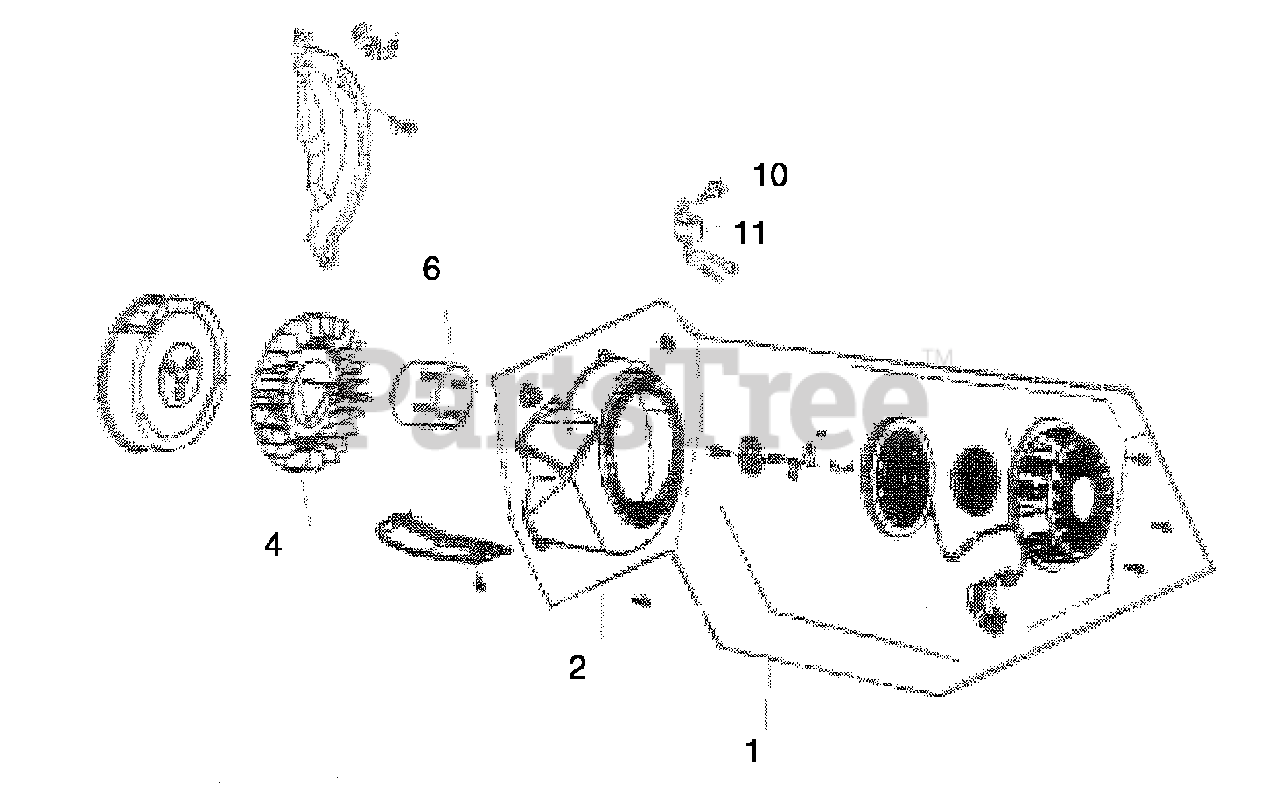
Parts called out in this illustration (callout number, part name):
1	STARTER ASSY, RECOIL
2	COVER COMP., FAN
4	FAN, COOLING
6	STARTING CUP
10	ALERT UNIT, OIL
11	BOLT, FLANGE 6X12
